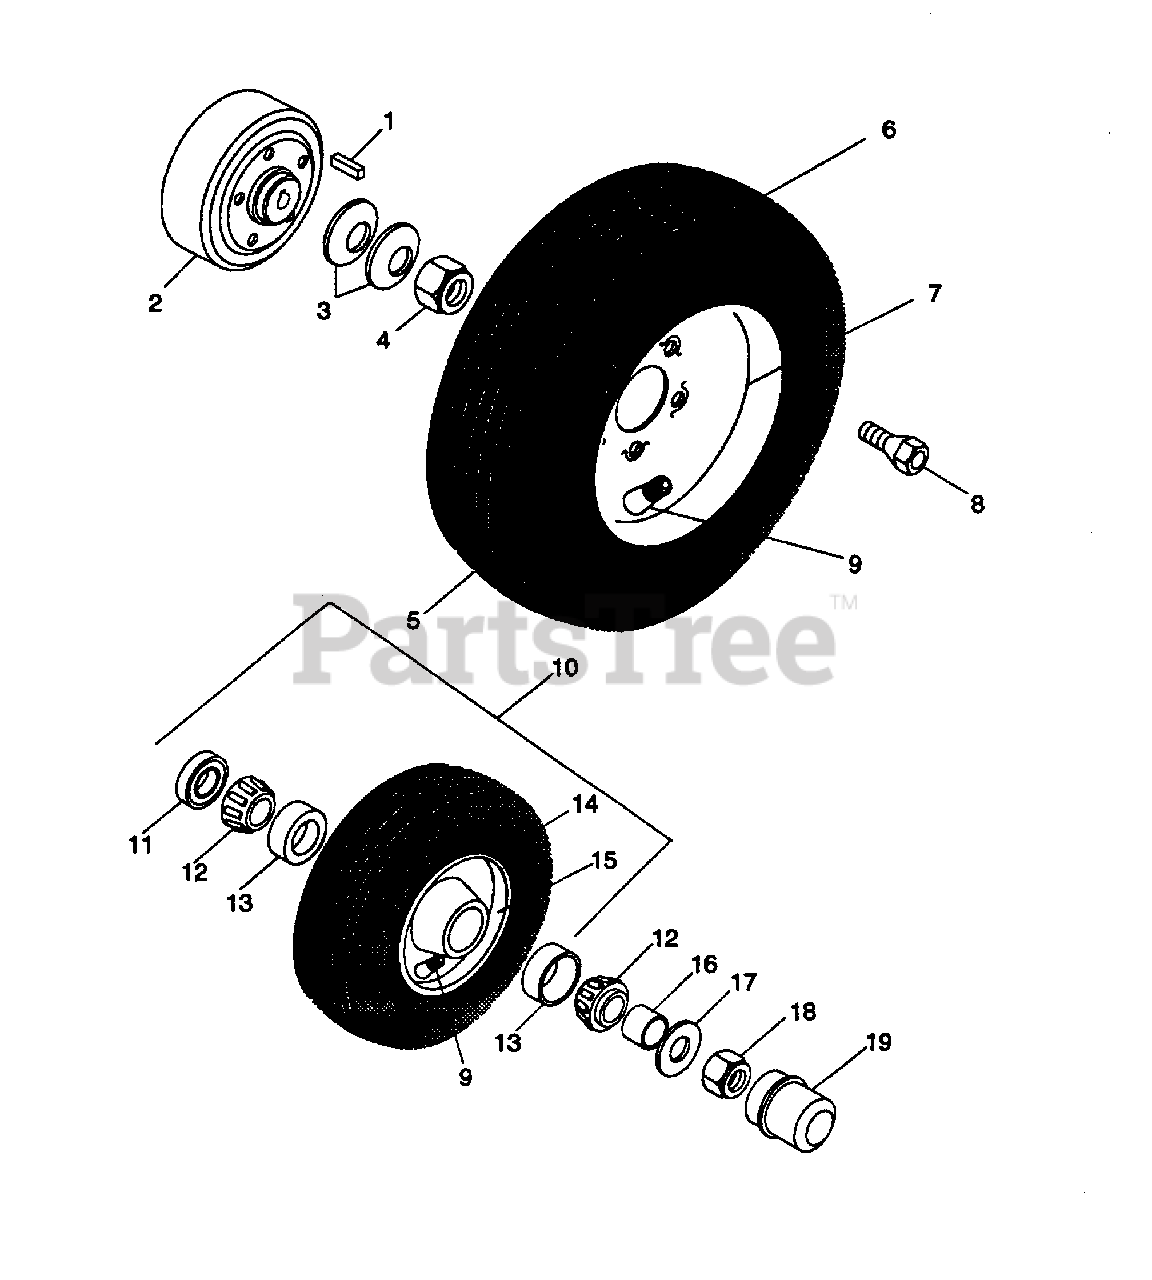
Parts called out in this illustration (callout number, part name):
1	KEY-SQ .312 X 2.25
2	HUB, WHEEL
3	SPRG, BELLEVILLE
4	NUT-LK 1.0-14 WSHR INSERT
5	T/WHL ASSY 23 X 10.50-12
6	TIRE, REAR 23 X 10.50-12
7	WLDMT, RIM
8	BLT .44-20 X 1.0
9	VALVE STEM ASS'Y
10	TIRE, ASSEMBLY
11	SEAL 1.206 X 1.785 X .486
12	BRG-CONE .750 X .61
13	BRG-CUP 1.781 X .475
14	TIRE, FRONT 16 X 7.50 - 8
14	TIRE, 15 X 6-6 4P RB TL
15	WELDMENT, RIM
17	WSHR-FL-STL .656 X 1.312 X .095 PL
18	NUT-LK-CTR .625-11 PL
19	DUST CAP
